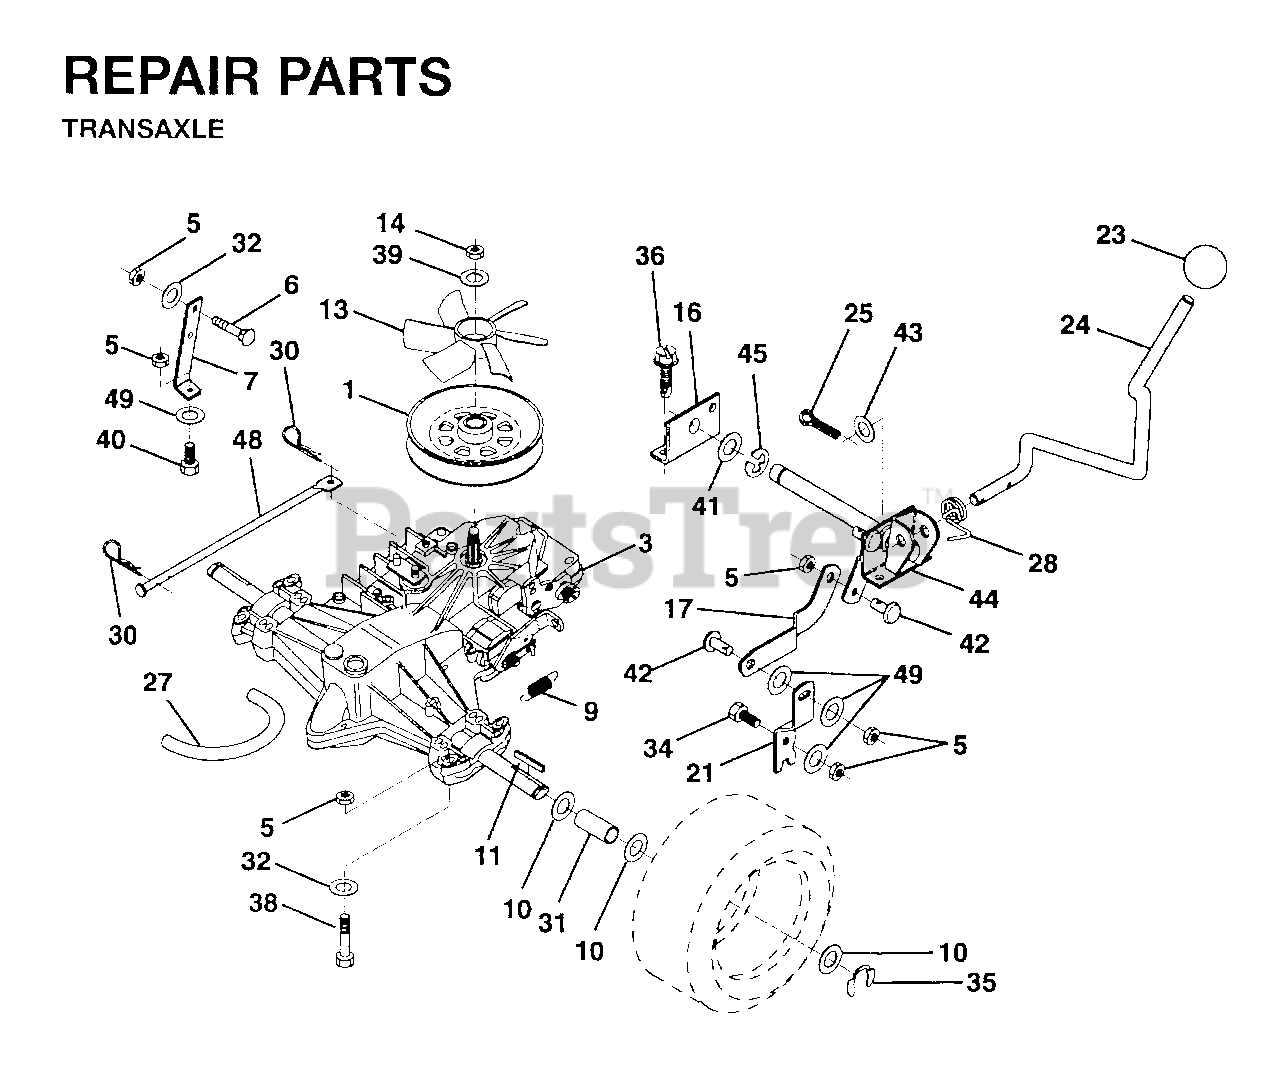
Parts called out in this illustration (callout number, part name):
3	TRANSAXLE HYDRO
5	NUT.71038.31-18.HEX.NYLOCK
6	BOLT
9	SPRING T
11	SQUARE KEY
13	FAN.TRANSMISSION.HYDRO.6"
16	SUPPORT, SHIFT HANDLE
17	LINK, SHIFT
21	LEVER, SHIFT
23	KNOB.DELUXE.(PISTOL.GRIP).BLAC
24	ROD, SHIFTER
25	PIN COTTER
27	FUEL LINE
28	SPRING, TORSION
30	RETAINER M
31	SPACER SPLIT
32	WASHER - 15X7.3X1.6
35	E-RING LT
36	BOLT
40	HEX BOLT
44	SHAFT PIVOT ASMBLY
45	RETAINING RING LT
48	ACTUACTOR
49	WASHER - 15X7.3X1.6
